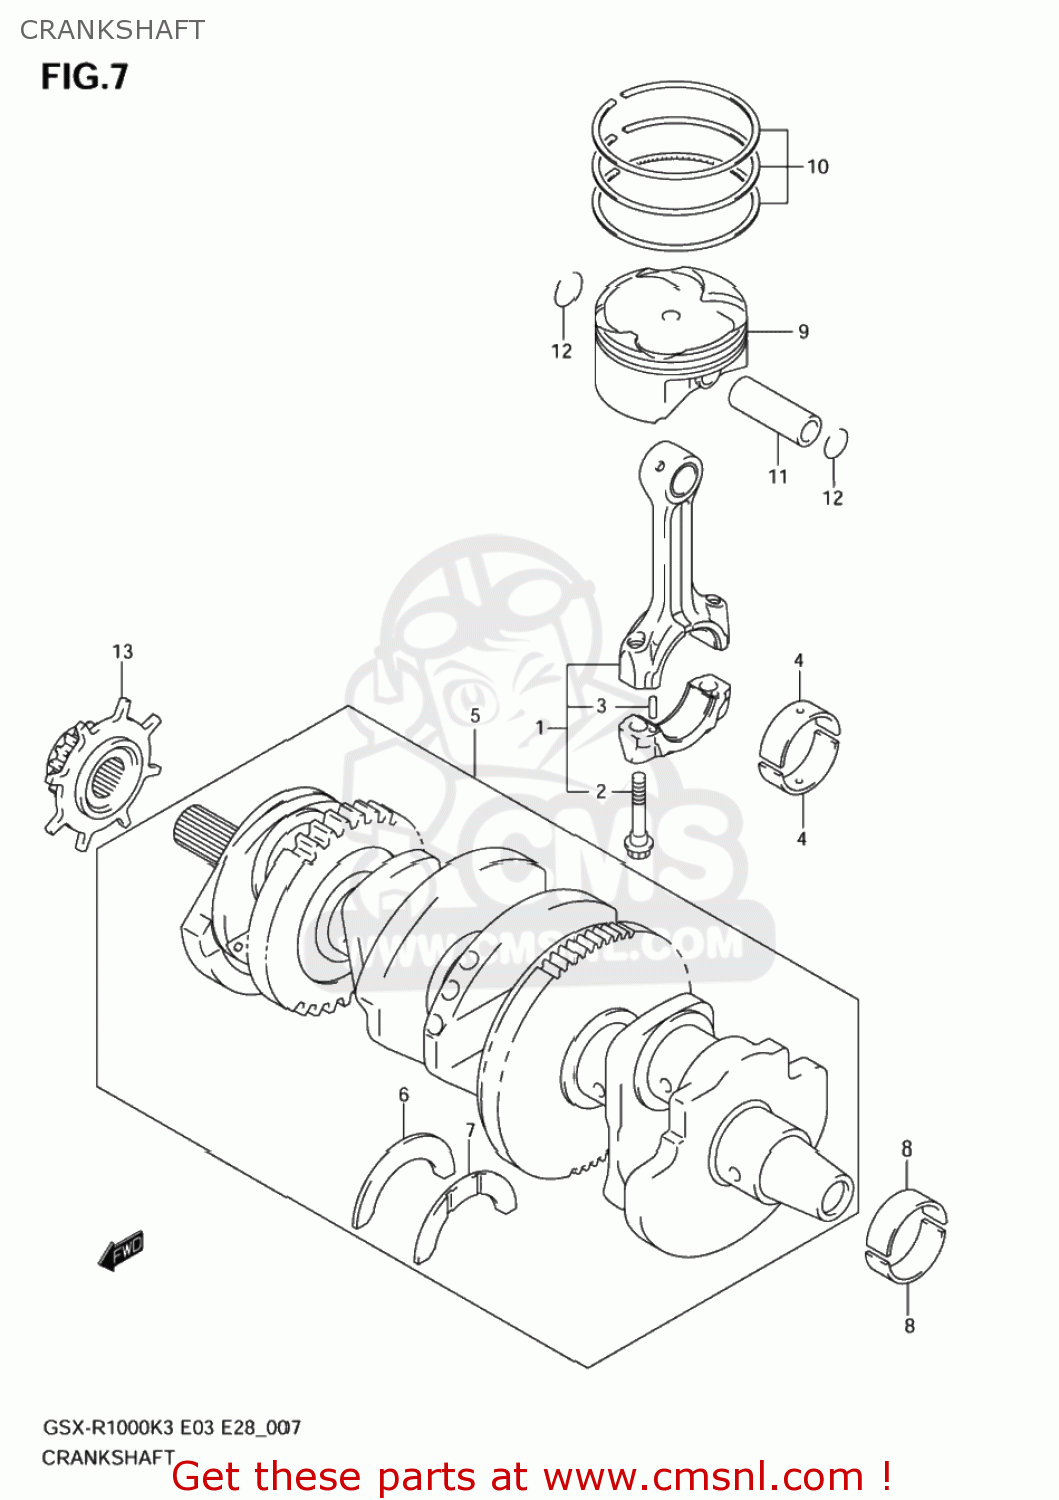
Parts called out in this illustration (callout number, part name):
1	CONNECTING ROD ASSY
2	BOLT,CONNECTING ROD
3	PIN,CONNECTING ROD
4	BEARING,CRANK PIN
5	CRANKSHAFT SET
6	BEARING,CRANK THRUST(GREEN)
7	BEARING,CRANK THRUST(RED)
8	BEARING,CRANKSHAFT
9	PISTON
10	RING SET,PISTON
11	PIN,PISTON
12	RING,SNAP 16MM
13	SPROCKET,CAM CHAIN DRIVE
